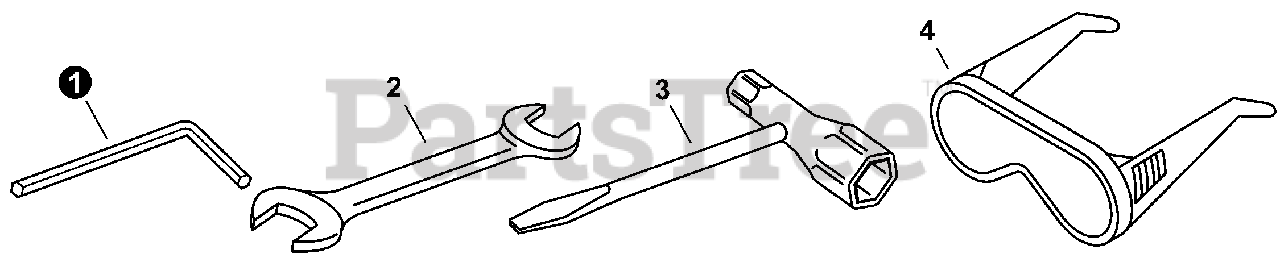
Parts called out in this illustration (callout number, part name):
1	WRENCH, ALLEN 4 MM
2	SPANNER 8×10
3	T-WRENCH 17×19 MM
4	GLASSES, SAFETY
